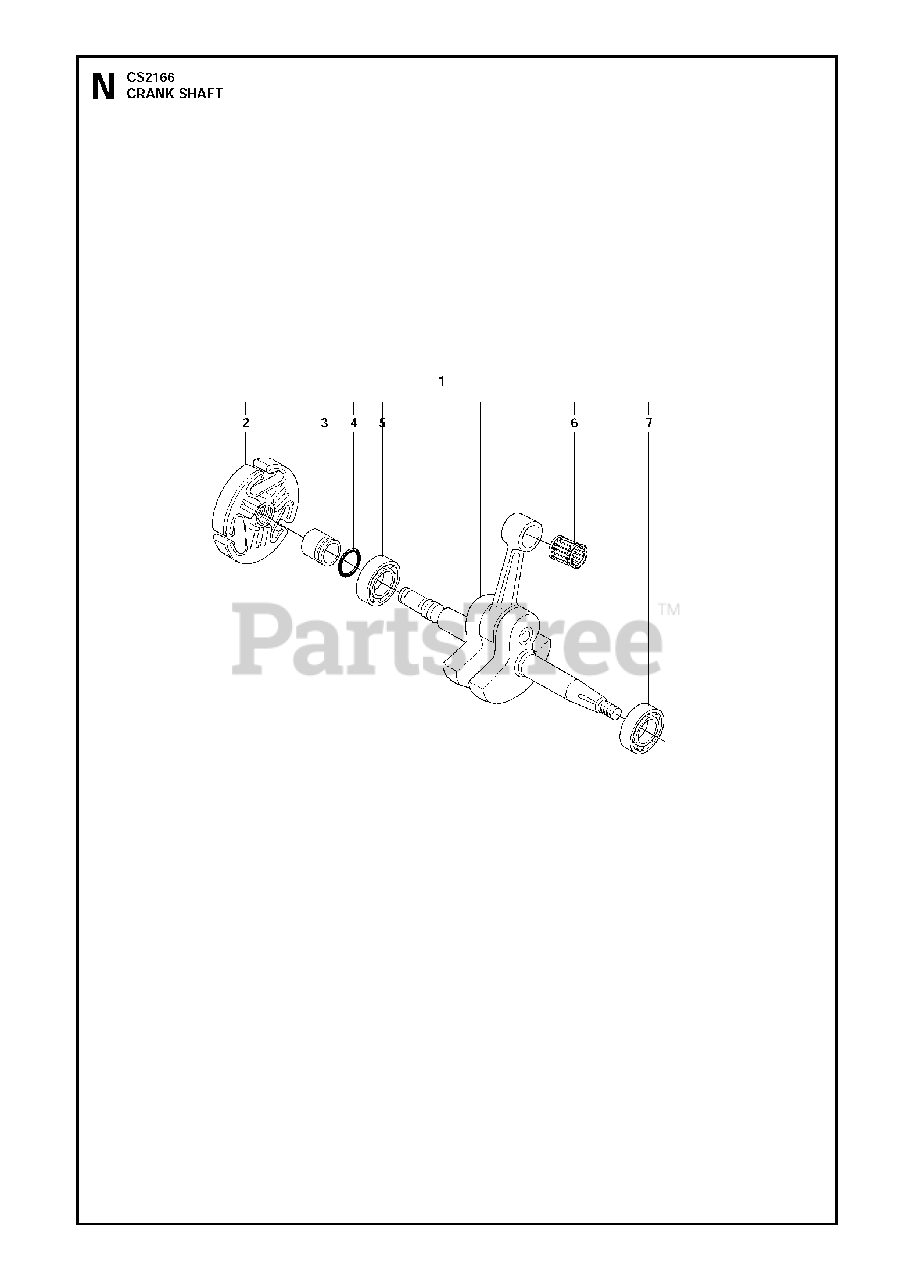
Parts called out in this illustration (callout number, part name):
1	CRANKSHAFT COMPLETE
2	CLUTCH
3	SLEEVE
4	O-RING
5	BALL BEARING
6	SUPPORT BUSHING
7	BALL BEARING
